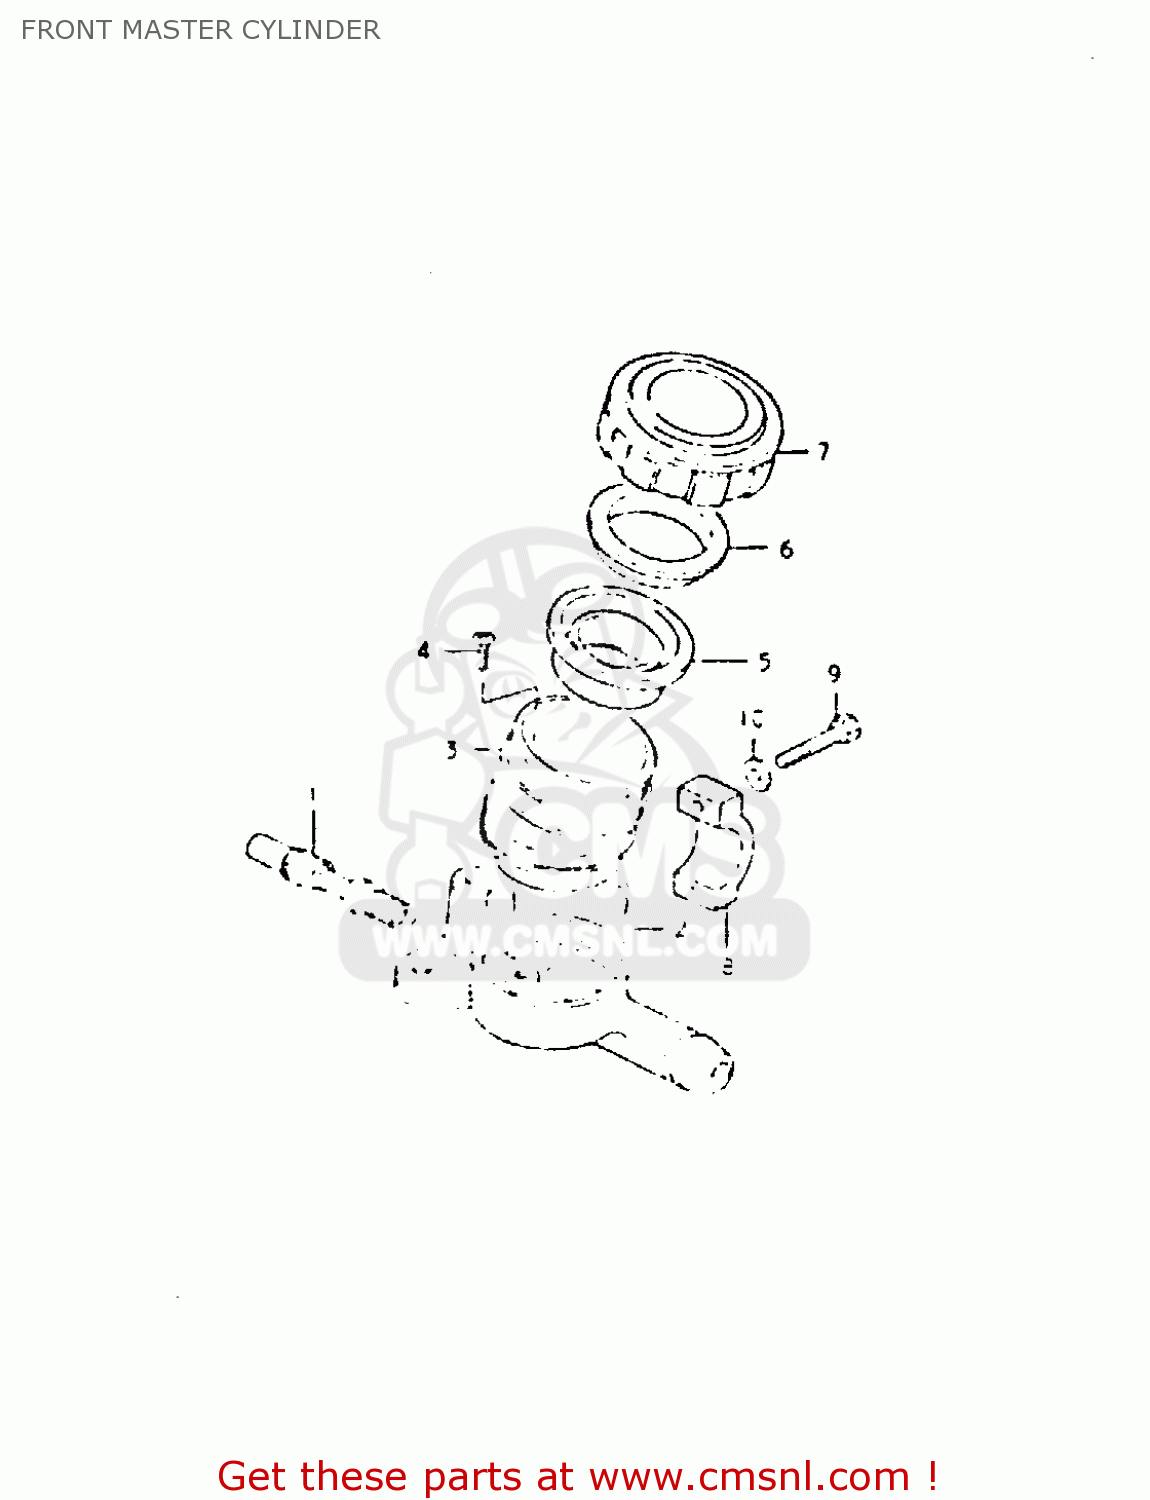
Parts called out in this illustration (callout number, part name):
1	PISTON & CUP SET
2	O RING
3	RESERVOIR
4	SCREW,MASTER CYLINDER
5	DIAPHRAGM
6	PLATE,DIAPHRAGM
7	CAP
8	HOLDER,MASTER CYLINDER
9	BOLT
10	WASHER
